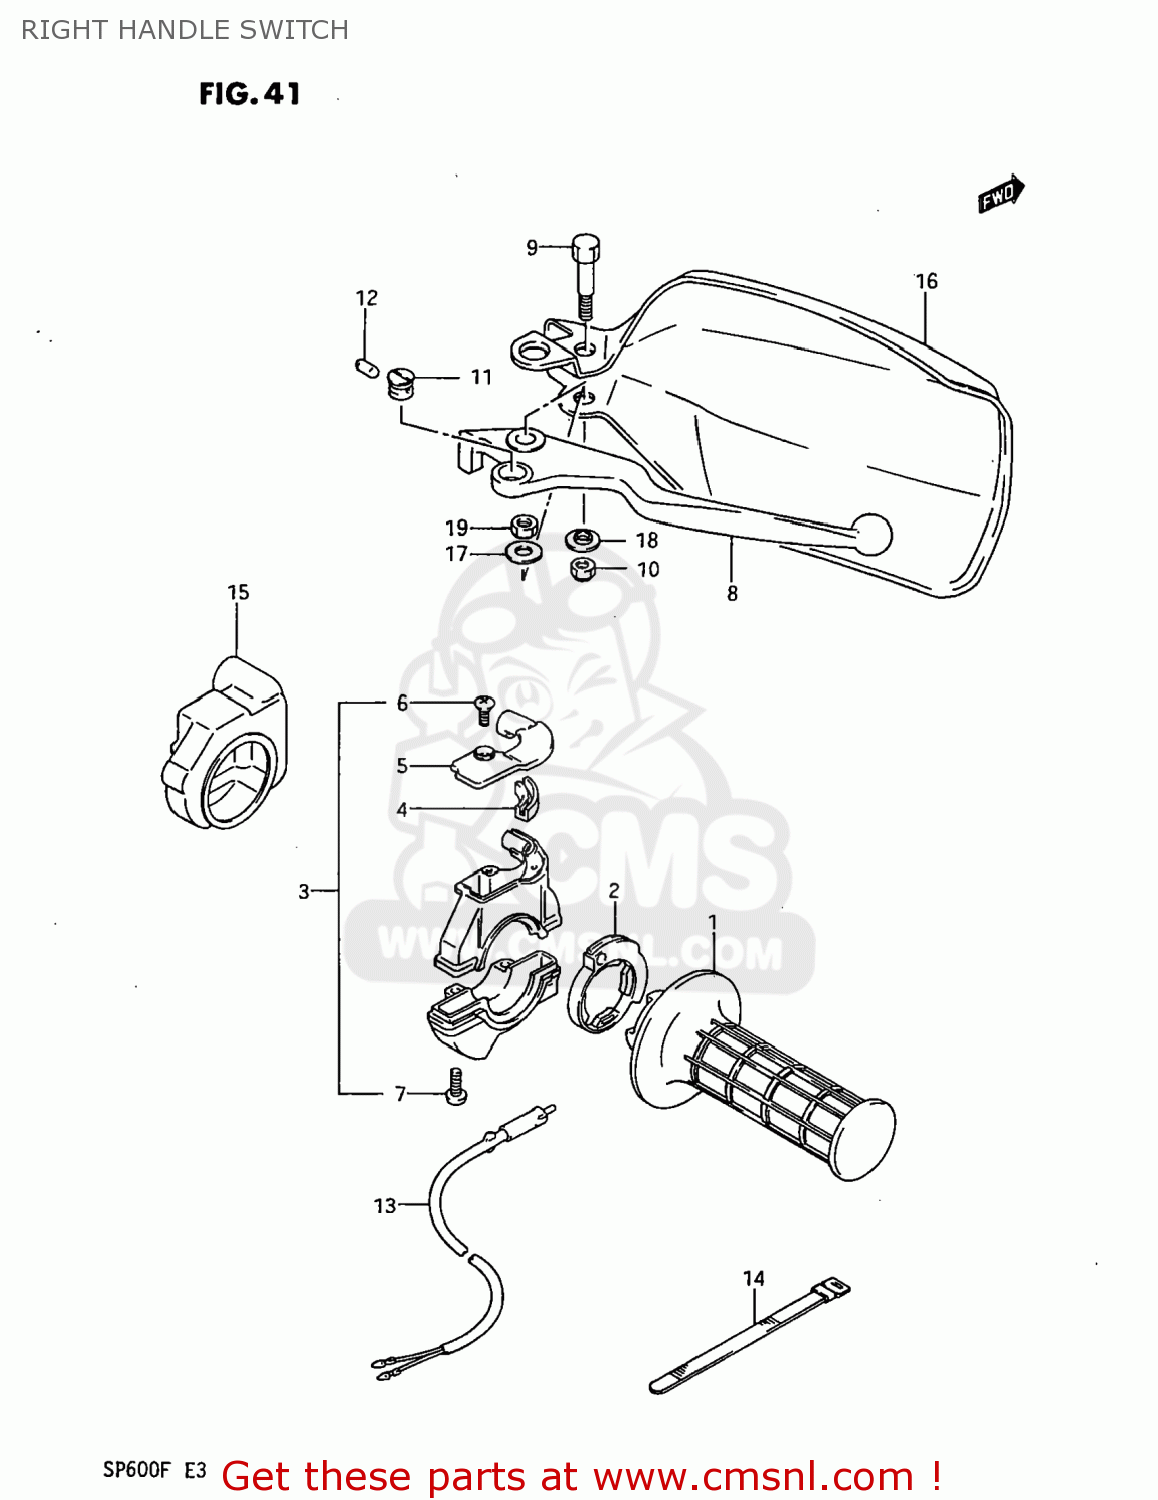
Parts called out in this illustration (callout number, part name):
1	GRIP,THROTTLE
2	ROTOR,THROTTLE GRIP
3	CASE ASSY,THROTTLE
4	GUIDE PIECE,THROTTLE
5	COVER,THROTTLE CASE
6	SCREW
7	SCREW
8	LEVER,BRAKE
9	BOLT,LEVER PIVOT
10	NUT
11	ADJUSTER
12	ROD,PUSH
13	SWITCH ASSEMBLY
14	CLAMP(L:120)
15	COVER,THROTTLE CASE
16	COVER,KNUCKLE,RIGHT
17	WASHER(6.5X16X1.2)
18	WASHER
19	NUT 6MM
